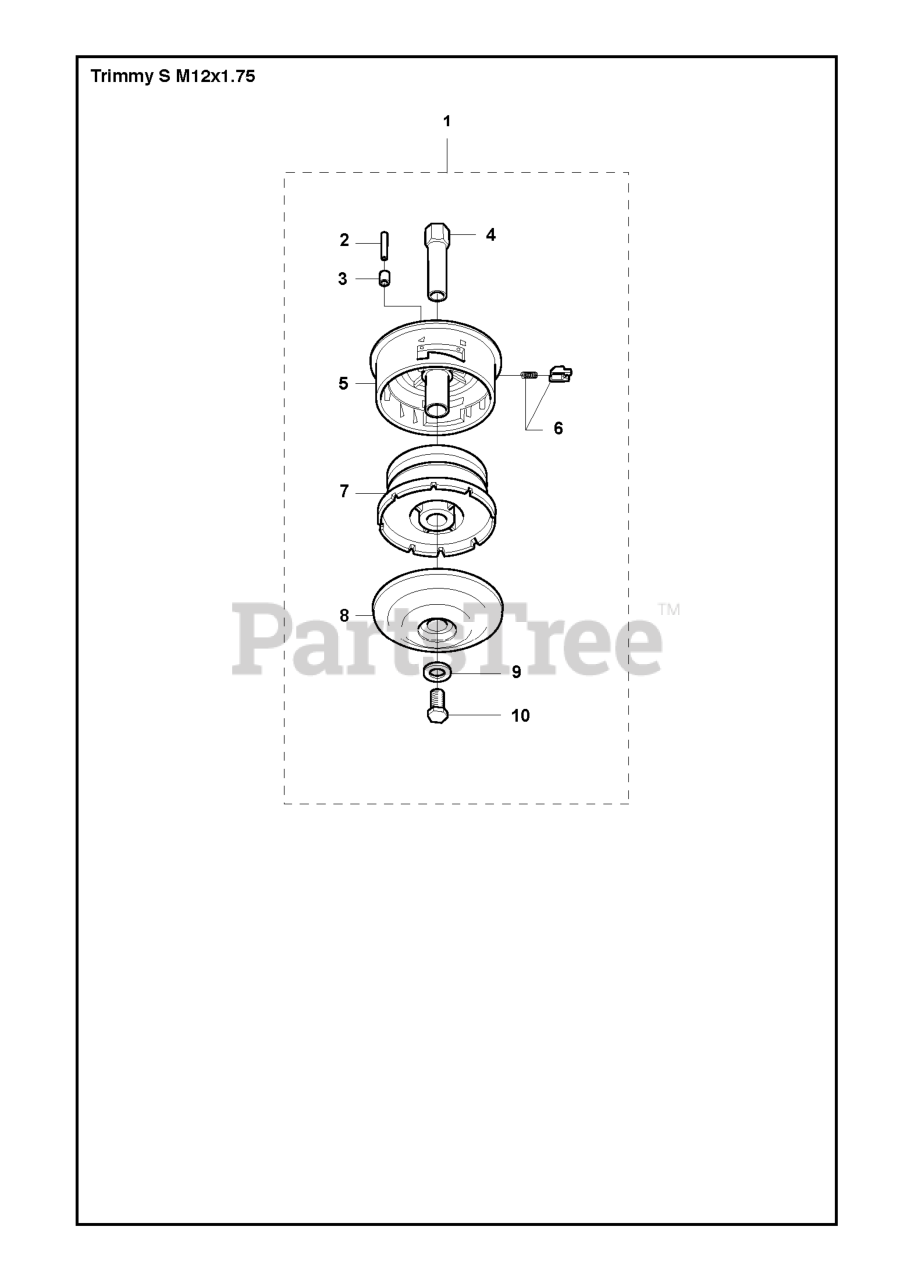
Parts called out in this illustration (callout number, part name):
1	Trimmy S
4	Adapter M10 Hexagonal
4	SHAFT M12 HEXAGONAL
6	CATCH W/ SPRING
8	SUPPORTING CUP
